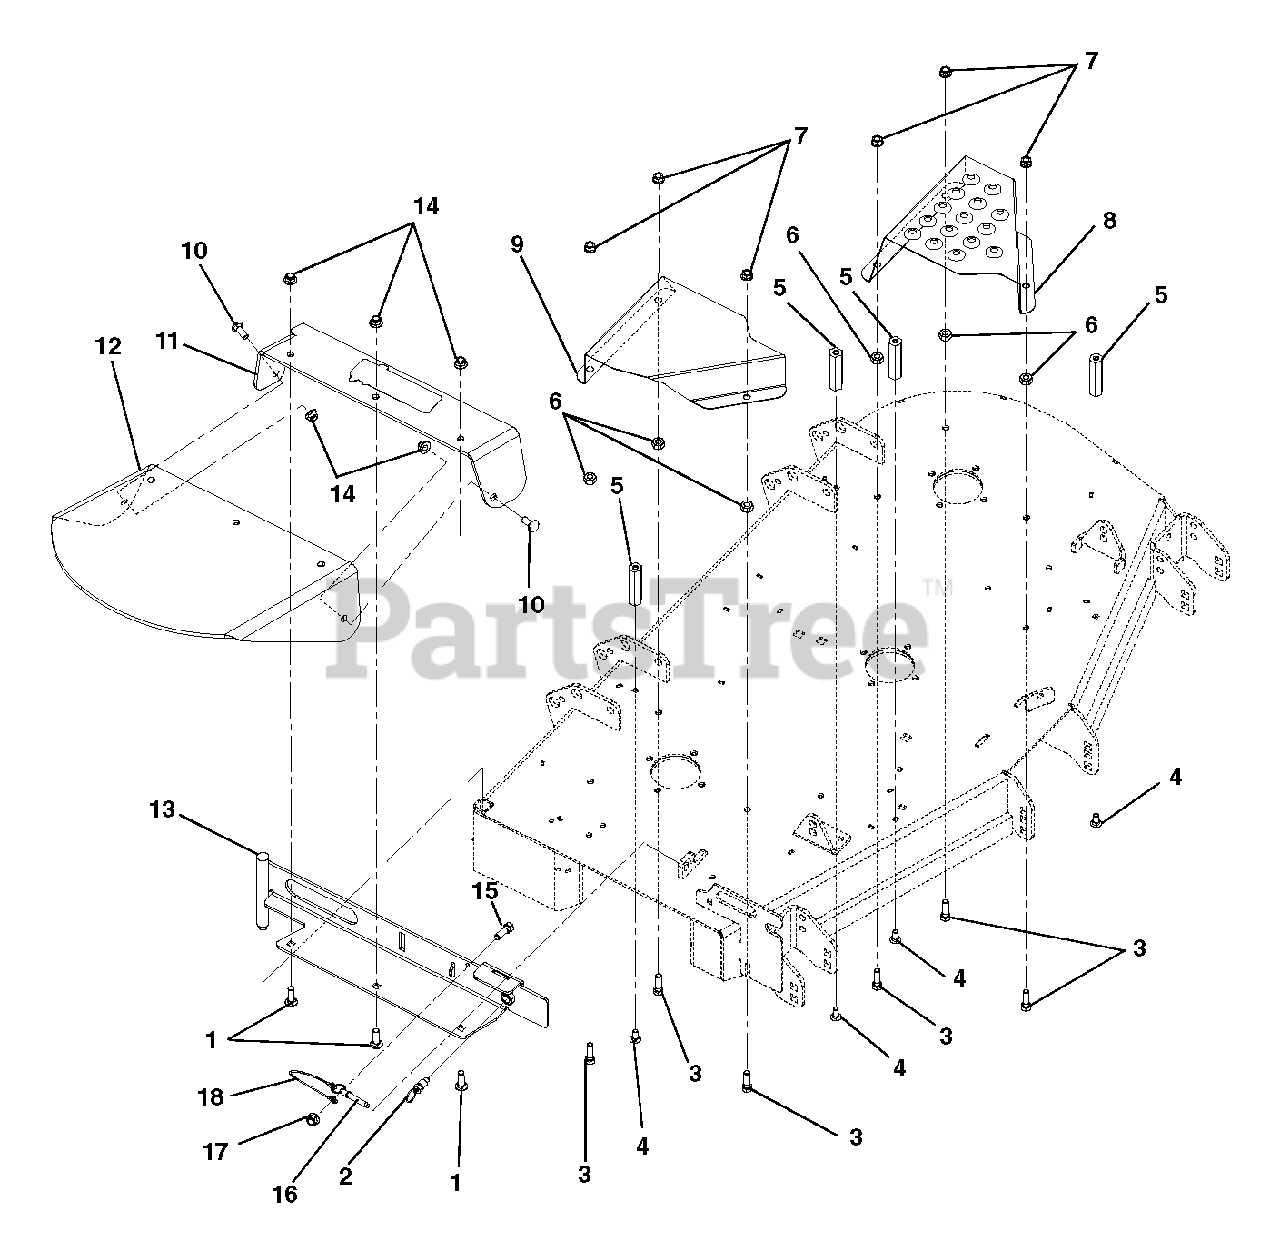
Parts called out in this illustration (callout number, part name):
1	Bolt, Round Head Square Neck .38-16 x 1.25 Grade 5
2	Pull Pin
3	Bolt, Hex .38-16 x 1.25 Grade 5
4	Bolt, Round Head Square Neck .31-18 x .75
5	Nut, Coupling .31-18 x 3.00
6	Nut, Heavy Hex .38-16
7	Nut, Flange .375-16
8	Guard,Left Hand Deck Belt,44-52 (076, 077)
9	Guard, 44-52 Right Hand Spindle Sheave (076)
10	Bolt, Round Head Square Neck .38-16 x 1.00 Grade 5
11	Rubber Discharge Chute Support
12	Chute, Rubber Discharge
13	Weldment, 48" Discharge Chute Support (076)
14	Nut, .38-16 Nyloc Flange
15	Bolt , Hex .25-20 x .75 Grade 5 (076)
16	Pin, Spring Ball .375OD x 1.50 (076)
17	Nut, Locking-Top-Flange .25-20 (076)
18	Cable, 6.0 Lanyard, Nylon (076)
